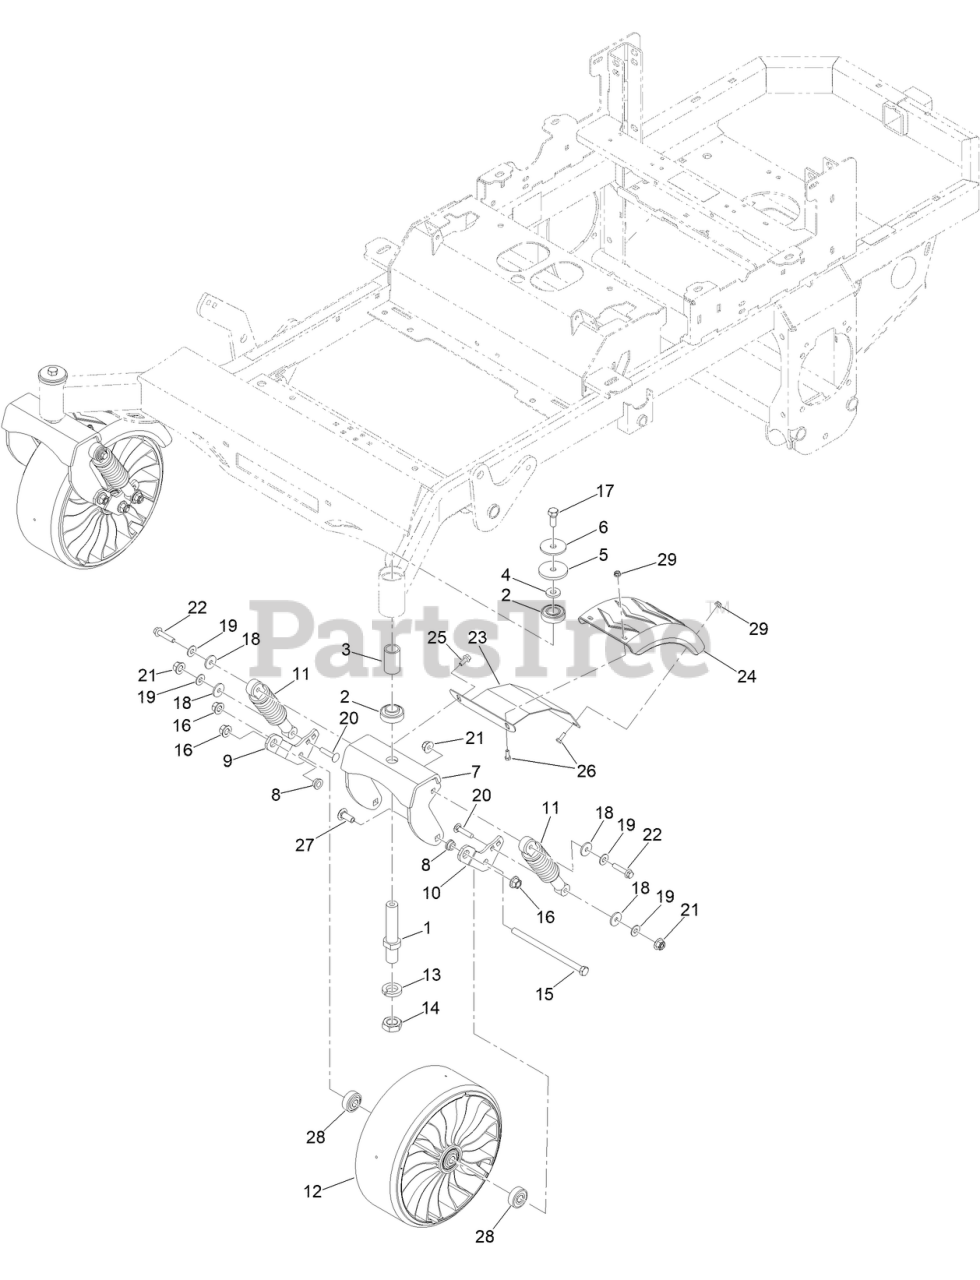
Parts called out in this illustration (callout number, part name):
1	MWR CASTER SHAFT
2	BEARING-BALL
3	CASTER FORK SHAFT BEARING SPACER
4	1/2 FENDER WASHER 1-1/4IN OD ZINC
5	FT HUB PLASTIC WASHER
6	MWR CASTER SHAFT WASHER BLACK
7	2022 FT FORK SHOCK ASSY BLACK
8	1/2IN ID X 3/4IN OD X 3/8IN FLANGE BUSH
9	2022 SRT TWEELS SUSP BRKT RT BLACK
10	2022 SRT TWEELS SUSP BRKT LT BLACK
11	2020 RZ PRO SEAT / FT FORK SHOCK
12	FRT TWEEL SMOOTH CASTER 13X6.5N6 (36271)
13	1IN L/W MED SPLIT ZC
15	1/2-13 X 8-1/2 HEX C/S GR 5 ZINC YELLOW
16	NUT-LOCK
17	1/2-20 X 1-1/4 HEX FLANGE BOLT GR 8 YZ
18	FLT WASHER 1.25ODX.38IDX.125 THK PLA
19	WASHER-FLAT
20	3/8IN-16X1-3/4IN G8 CARRIAGE BOLT
21	3/8-16 NYLON INSERT FLANGE L/NUT YZ
22	3/8-16 X 1-.75 HEX FLG BOLT GR 8 YELLOW
23	2020 SPARTAN FT FENDER BRKT BLACK
24	SPARTAN FORK FT FENDER
25	SCREW-HHF
26	SCREW-HH
27	1/2-13 X 1.25 CARRIAGE BOLT YELLOW
28	BUSHING SET FOR FT TWEEL 38182
